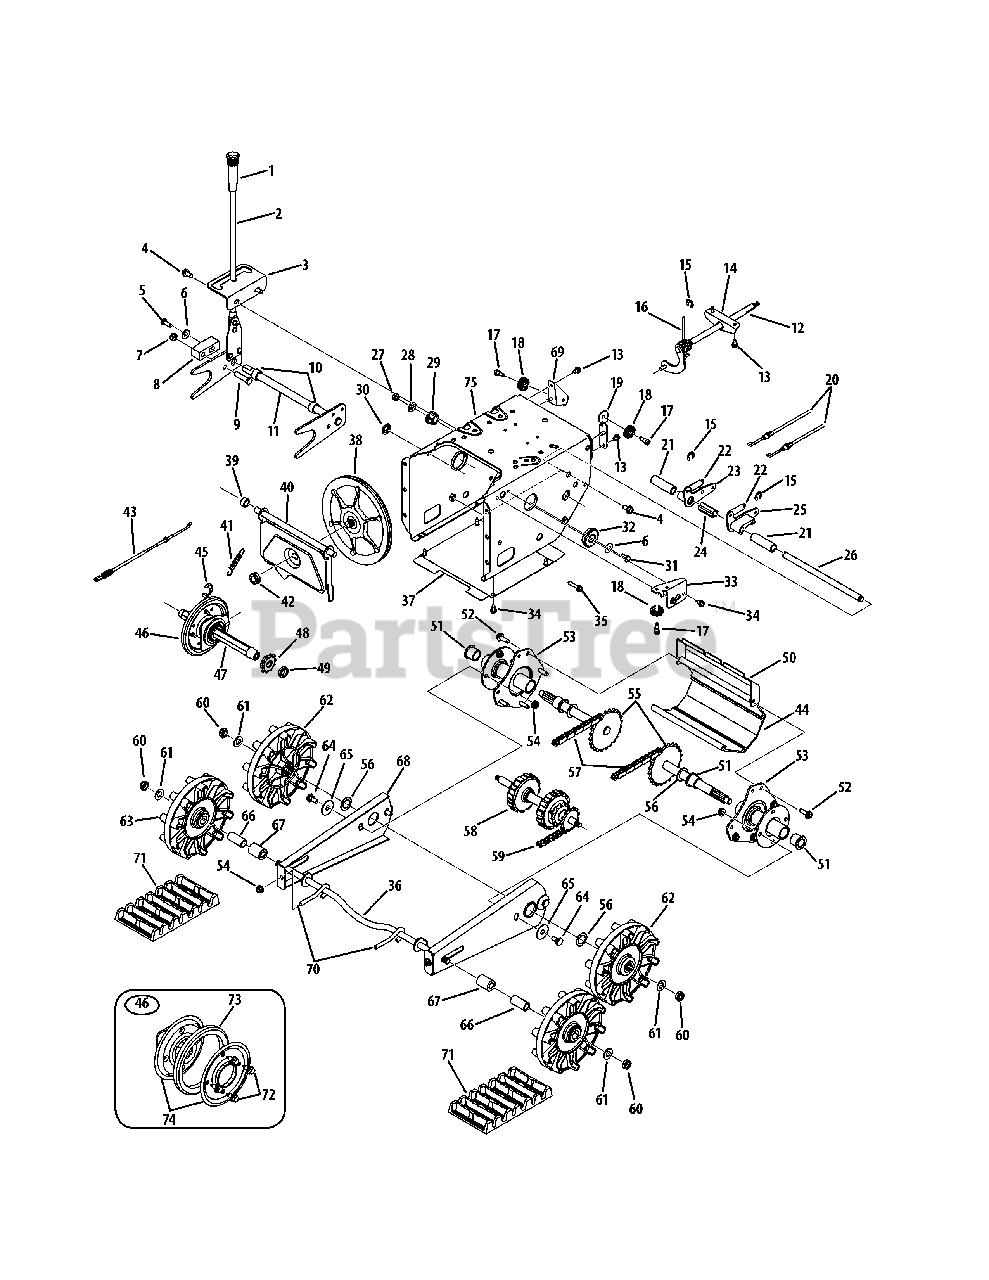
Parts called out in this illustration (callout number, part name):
1	Grip, .5 ID x 3.45
2	Track Lock Handle Assembly
4	Hex Washer Screw, 5/16-18 x .750
5	Hex Screw, 5/16-24 x .75
6	Bell Washer, .340 x .872 x .060
7	Hex Lock Nut, 3/8-16
8	Lift Shaft Drive
9	Hex Screw, 3/8-16 x 1.50
10	Spacer, .828 ID x .875 OD x .500
11	Pivot Rod Assembly
12	Shift Rod Assembly
13	Hex Washer Screw, 1/4-20 x .500
14	Shift Frame Bracket
16	Torsion Spring, .750 ID x .968
17	Shoulder Screw, .34 x .335 x 1/4-28
18	Cable Roller
19	Auger Cable Guide Bracket
20	Track Steering Cable
21	Spacer, .515 x 735 x 2.44
22	Extension Spring, .48 OD x 2.03
23	Dogg Assembly, RH
24	Spacer, .491 ID x 1.87
25	Dogg Assembly, LH
26	Shift Actuator
27	Jam Lock Nut, 3/8-24
28	Flat Washer, .406 x .875 x .059
29	Hex Flange Bearing
30	Speed Nut, .500
31	Hex Lock Screw, 5/16-18 x .625
32	Ball Bearing
33	Auger Cable Support Guide
34	Hex Washer Screw, 1/4-20 x .625
35	Hex Washer Screw, 1/4-20 x 1.000
37	Track Frame Cover
38	Friction Wheel Disc Assembly
39	Spacer, .525 ID x .750 x .42
42	Flange Nut, 5/16-18
43	Drive Clutch Cable
46	Friction Wheel Assembly
47	Hex Track Shaft
48	Sprocket, 10T
49	Spacer, .675 ID x 1.00 OD x .23
52	Hex Washer Screw, 5/16-18 x 1.0
53	Track Hub Assembly
54	Flange Lock Nut, 5/16-18
55	Track Axle Assembly
56	Flat Washer, .793 x 1.24 x .06
58	Drive Track Shift Assembly
60	Jam Lock Nut, 1/2-20
61	Flat Washer, .510 x 1.00 x .060
62	Track Drive Wheel
63	Track Idler Wheel
64	Shoulder Screw, .43 x .56 5/16-18
65	Flat Washer, .442 x 1.38 x .060
66	Spacer, .51 ID x .75 OD x 1.67
67	Spacer, .510 ID x 1.0 OD x 1.34
69	Drive Cable Guide Bracket
70	Eye Bolt, 5/16-18 x 3.0
71	Snow Trac
72	Hex Washer Screw, 1/4-14 x .625
73	Friction Wheel
74	Friction Plate
75	Frame Assembly
